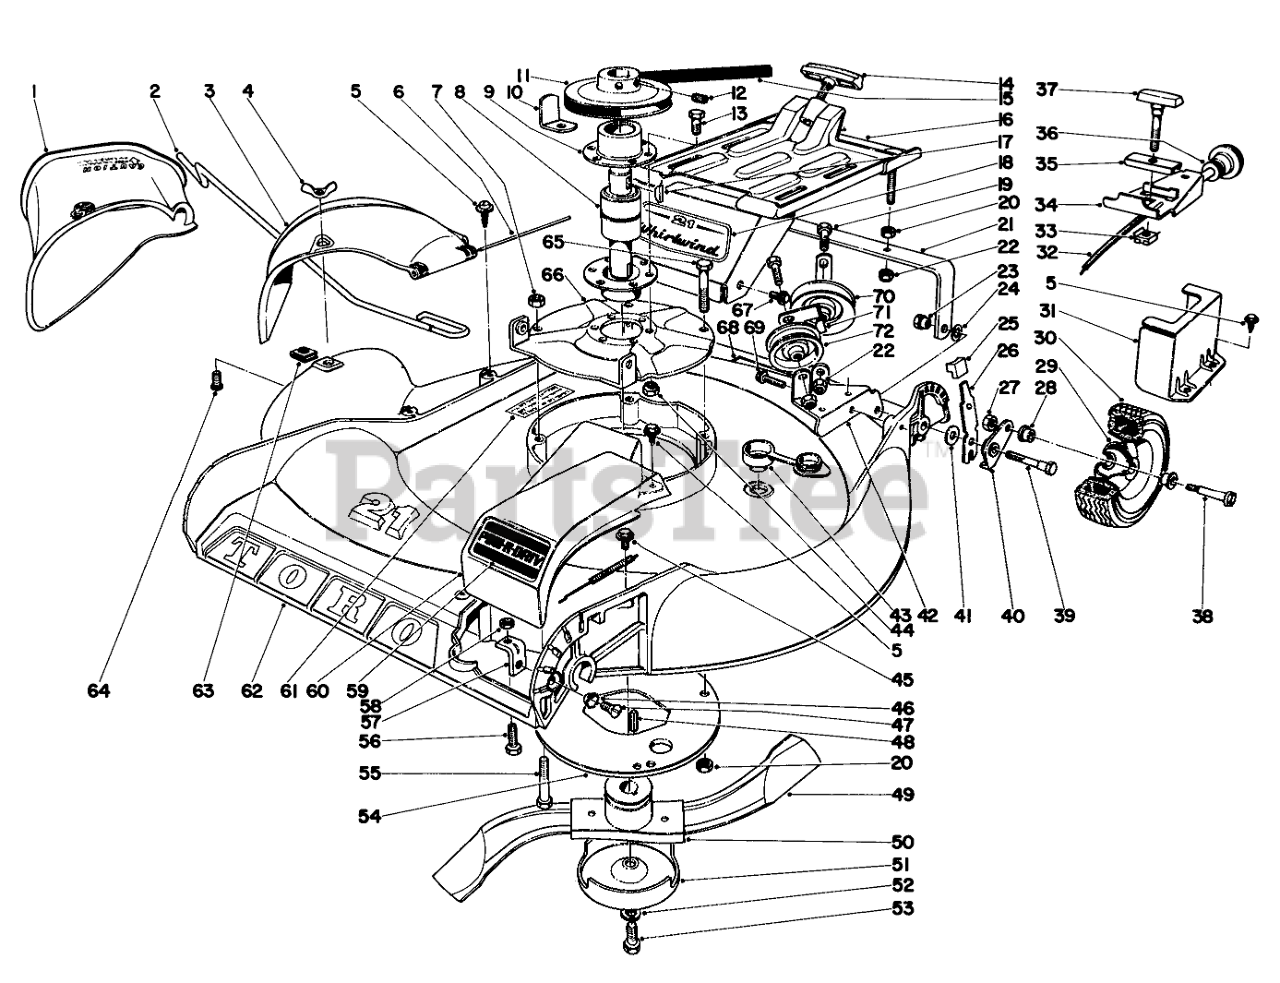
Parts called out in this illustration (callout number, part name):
1	Attachment Bag
2	Bag Hanger
3	Deflector
4	NUT-WING SPECL
5	Screw
6	HINGE PIN
7	NUT-HF
8	Spindle Bearing
9	BEARING HOUSING
10	Belt Retainer
11	Pulley
12	SCREW-SET, HSH
13	SCREW-HH
14	Clamp Assy.
15	V-Belt
16	Adapter Plate
17	KEY-WOODRUFF
18	Decal
19	SCREW-HH
20	NUT-HEX
21	Rear Support
23	Pivot Nut
24	WASHER-LOCK, INTERNAL
26	Spring Arm
27	NUT-HEX
28	Bushing
29	Wheel Assy. (Incl. No. 28)
30	8 TIRE
31	Belt Guard
32	Control Assy
33	Retaining Nut
34	Angle Bracket
35	Strap
36	WASHER-FLAT
37	Clamp Assembly
39	Pivot Screw
40	Pivot Arm
41	Washer
42	Idler Bracket
43	Washer Plug
44	NUT-LOCK, NI
45	SCREW-HHF
46	Lockwasher
49	Blade
50	Retainer
51	Scalp Cup
52	WASHER-LOCK
53	SPECIAL SCREW
54	Grass Guard
55	SCREW-HH
56	SCREW
57	ADJ BRACKET
58	NUT-JAM
59	Decal
60	Belt Guard
61	Decal
62	Housing
63	NUT-SPEED
65	Screw
66	Mounting Plate
67	Sems Screw
68	Serial Number Plate
69	Sems Screw
70	IDLER PULLEY R
71	Belt Retainer
72	PULLEY-IDLER
